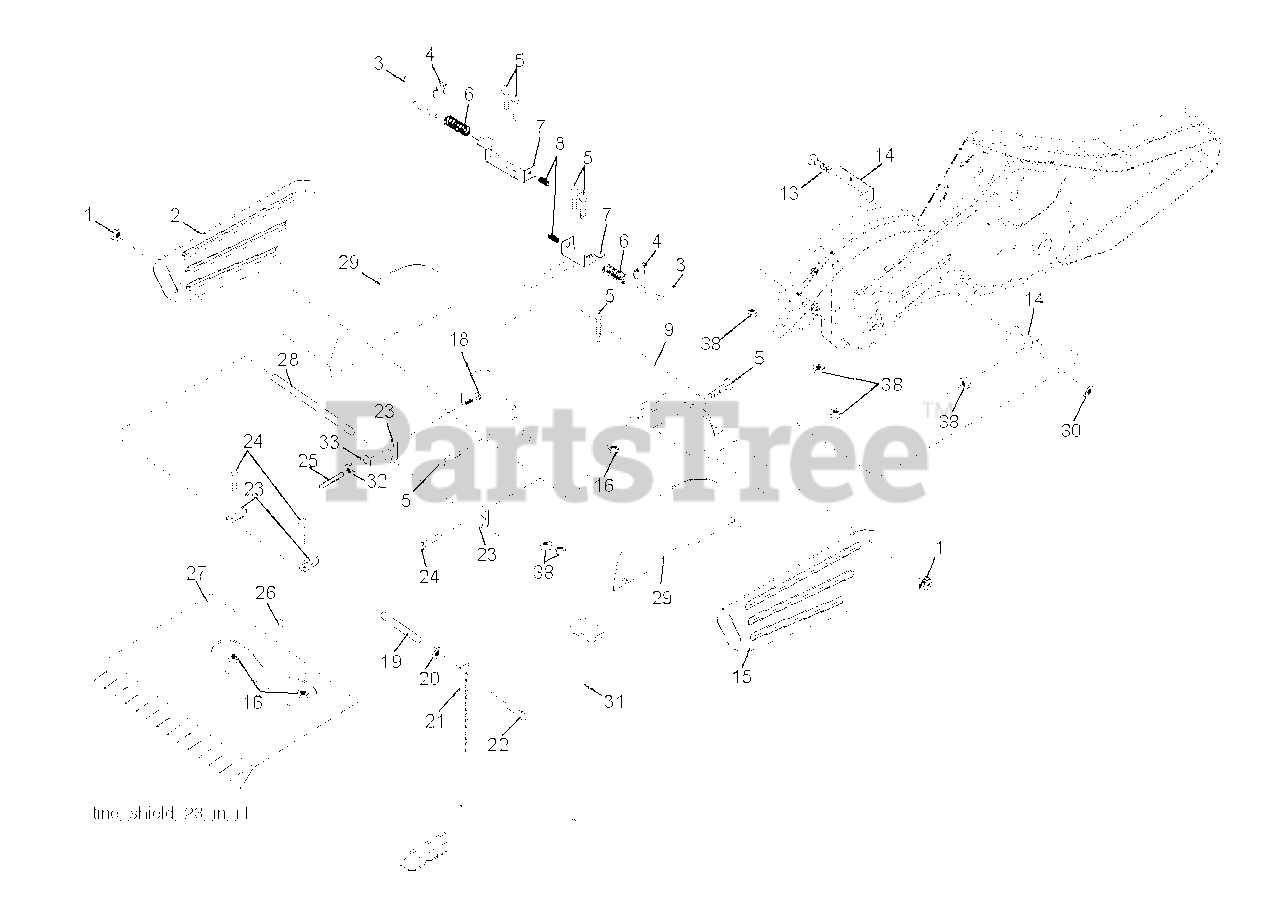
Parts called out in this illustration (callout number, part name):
1	NUT LOCK HEX FLANGE 5/16-18
3	STAKE PIN TI
4	RING, KLIP
5	BOLT, RDHD SQNK 5/16-18 X 3/4
6	SPRING TI
7	LATCH BRACKET TI
8	SPRING CRT
13	BOLT.CARRIAGE.5/16-18
14	BRACKET.TINE.SHIELD.TILLER
15	SHIELD.SIDE.OUTER.RH.YELLOW
16	NUT T
19	GRIP CRT
20	NUT.HEX.3/8-16UNC
21	STAKE.DEPTH.16.CRT.BLACK
22	BOLT.375-16
23	HINGE CRT
26	PAD IDLER TI
27	SHIELD.LEVELING
28	PIN.HINGE.TILLER
29	SHIELD.ASM.TILLER.SIDE.YELLOW
30	LOCKNUT-FLANGE 5/16-18
31	RP STAKE.PNT.DEPTH.DRAG.GREY
32	NUT
33	LOCKWASHER
